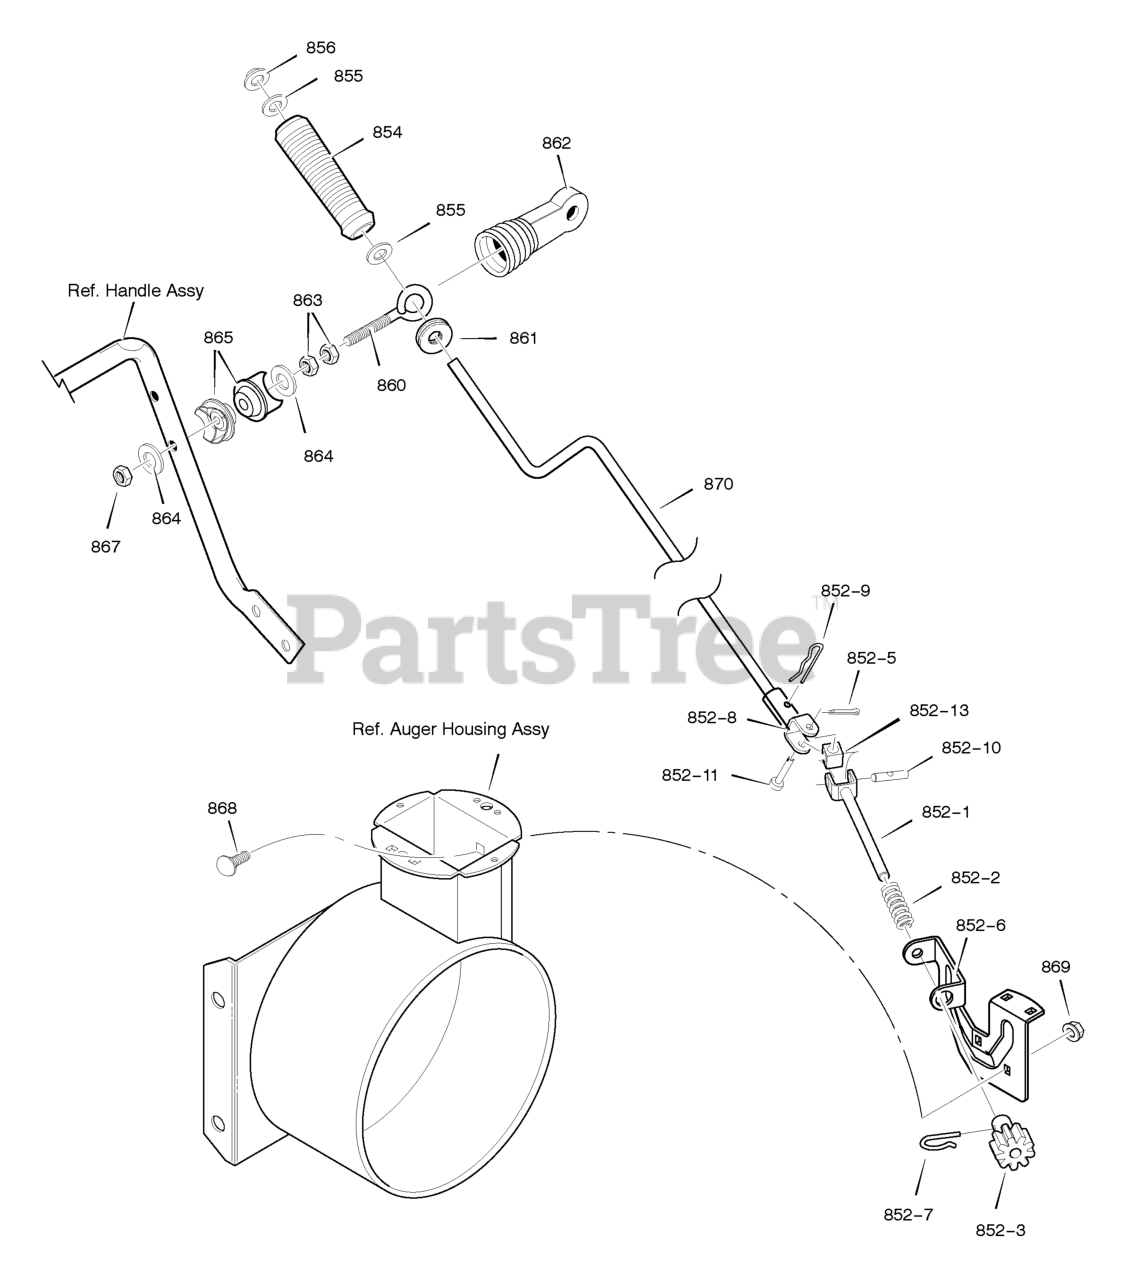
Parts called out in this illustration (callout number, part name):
852-1	ASSEMBLY, YOKE & ROD
852-3	GEAR, CHUTE ROTATION 9T
852-5	PIN,COTTER
852-6	BRACKET, CHUTE GEAR
852-7	PIN, HAIR
852-8	ASSEMBLY, YOKE ADAPTER YZ
852-9	PIN, HAIR
852-10	PIN, UNIVERSAL JOINT
852-11	PIN, CLEVIS
852-13	HOUSING, UNIVERSAL
854	KNOB, SLEEVE
855	FLATWASHER
856	NUT, PUSH ON 3/8"
860	EYE BOLT 3/8-16X6.00
861	GROMMET, EYE BOLT
862	BOOT, EYE BOLT
863	NUT, 3/8- 16 HEXJAM
864	FLATWASHER .406X.81X.066
865	ADAPTER, BOOT
867	NUT, 3/8- 16 HEXNYL
868	BOLT, CARRIAGE 1/4-20 X 1.00
869	NUT, 1/4-20
870	CRANK, ASSY CHUTE
